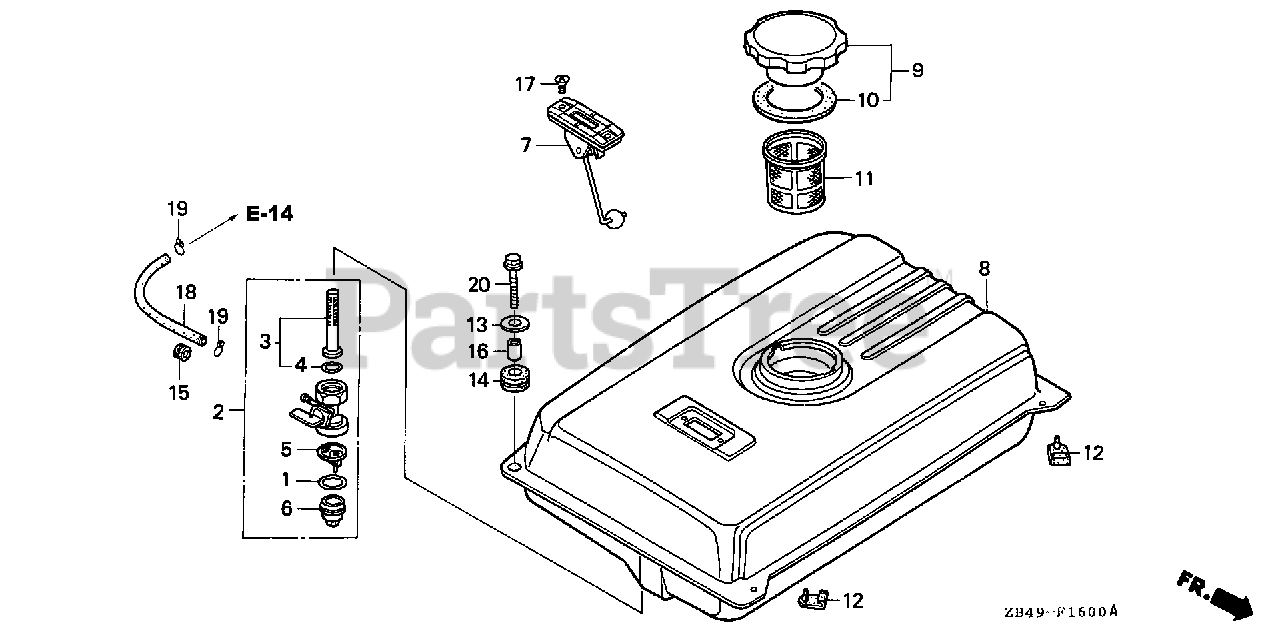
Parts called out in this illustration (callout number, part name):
1	GASKET, FUEL STRAINER CUP
2	PETCOCK ASSY.
3	SCREEN SET, FUEL STRAINER
4	O-RING (9.0X1.3)
5	FILTER, CUP
6	CUP, FUEL STRAINER
7	METER ASSY., FUEL
8	TANK, FUEL *R280* (POWER RED)
9	CAP, FUEL FILLER
10	GASKET, FUEL FILLER CAP
11	FILTER, FUEL
12	RUBBER, TANK MOUNTING
13	WASHER, TANK CUSHION
14	RUBBER, TANK CUSHION
15	RUBBER, FUEL (9X15X20)
16	COLLAR, TANK CUSHION
17	SCREW, FLAT (5X10)
18	BULK HOSE, FUEL (4.5X3000) (4.5X150)
19	CLIP, TUBE (B8)
20	BOLT, FLANGE (6X22)
